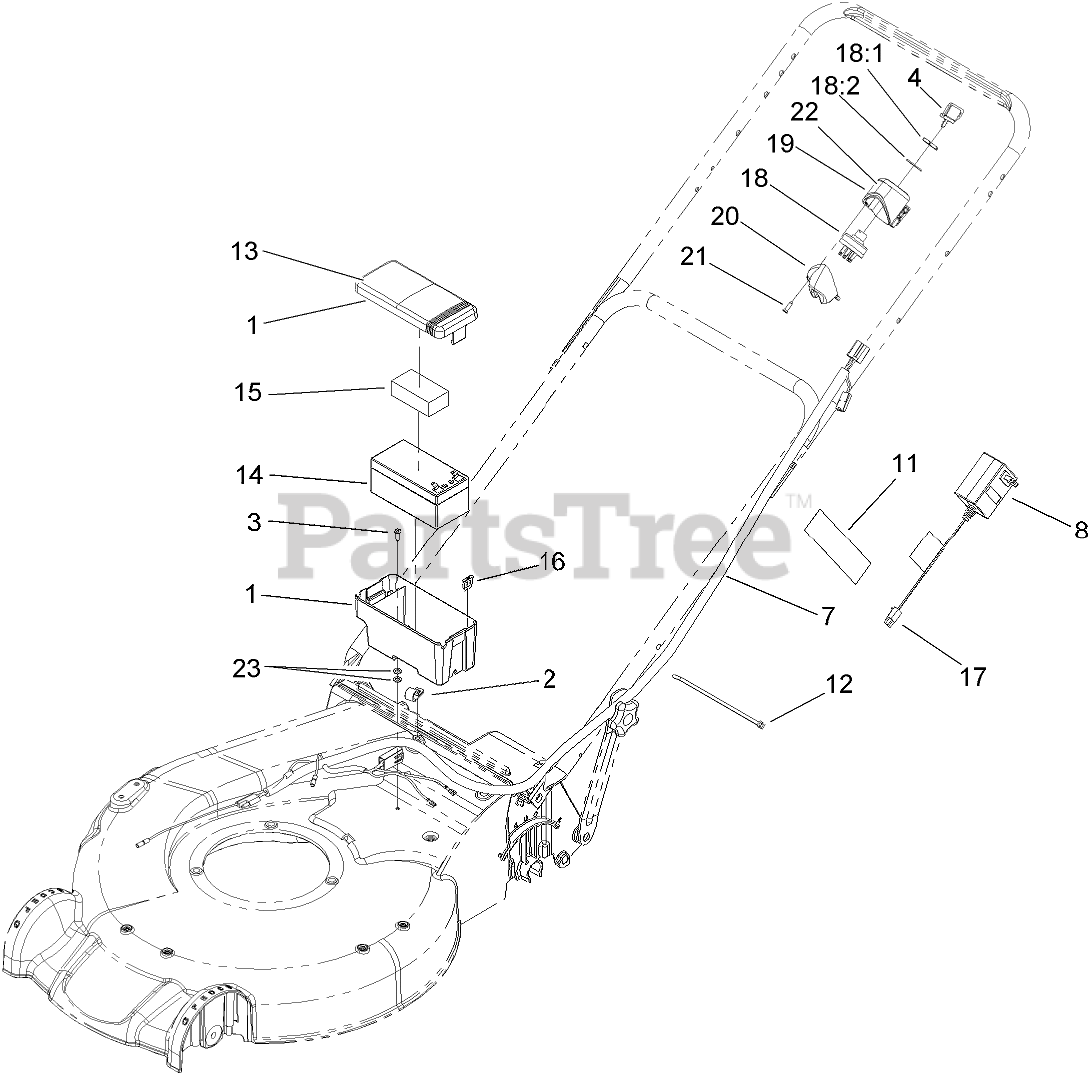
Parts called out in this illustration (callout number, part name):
1	BATTERY BOX ASM
2	CLAMP-R
7	HARNESS-WIRE
8	CHARGER-EUROPEAN, 12V DC
11	DECAL-WARNING
12	TIE-CABLE
13	DECAL-INSTRUCTIONAL
14	BATTERY-WET
15	FOAM-BATTERY, TOP
16	FUSE-40 AMP
17	ADAPTER-CHARGER
18	SWITCH-STARTER
18:1	NUT-HH
18:2	WASHER-TOOTH, INTERNAL
19	HOUSING-SWITCH, KEY
20	COVER-SWTCH
21	SCREW-PPH
22	DECAL-SWITCH, IGNITION
23	WASHER-FLAT
